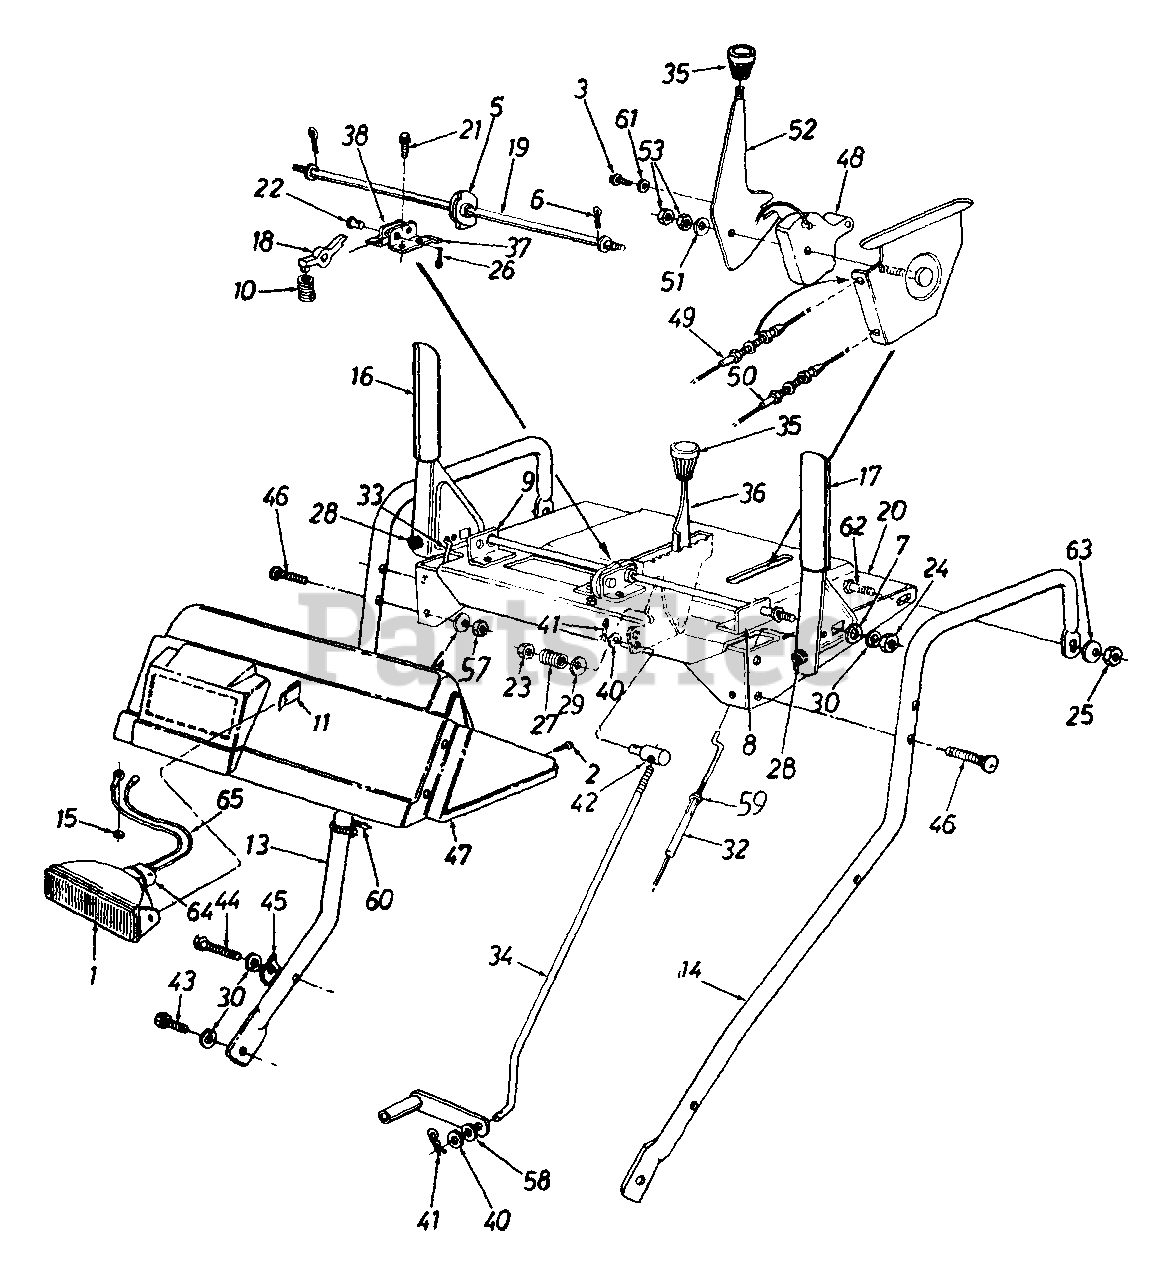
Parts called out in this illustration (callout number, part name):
1	Lamp Housing w/Lens
2	Truss Mach. B-Tap Scr. #10 x .5
3	Hex AB-Tap Scr. 1/4 x .62" Lg.
4	Bell - Wash. .325" I.D. x .88" O.D.
5	Cam Handle Lock
6	Cotter Pin 3/32" Dia. x .75" Lg.
7	Washer (Special) .72" O.D.
9	Handle Support Brkt. - R.H.
10	Compression Spring
11	Retaining Clip
13	Handle - R.H.
14	Handle - L.H.
15	Hex Sems Nut 1/4-20 Thd.t
16	Engagement Handle - R.H.
17	Engagement Handle - L.H.
18	Pawl Handle Lock
19	Rod Cam
22	Clevis Pin .437" Dia. x .65" Lg.
23	Hex Ins. L-Nut 3/8-24 Thd.
24	Hex Nut 5/16-18 Thd.
25	Hex Nut 1/4-20 Thd.
26	Cotter Pin 3/32" Dia. x 1" Lg.
27	Compression Spring
28	Rubber Bumper
29	Bell-Wash. .38" I.D. x .88" O.D.
30	L-Wash. 5/16" I.D.
31	Spring Wash. .265" I.D.
32	Auger Clutch Cable
33	Drive Clutch Cable
34	Shift Rod
35	Shift Knob
36	Shift Handle
37	Handle Brkt. - L.H.
38	Handle Brkt. - R.H.
40	Fl-Wash. .344" I.D. x .62" O.D.
41	Internal Cotter Pin 5/16" Dia
42	Ferrule
43	Hex Bolt 5/16-18 x .62" Lg. (Special)
44	Hex Bolt 5/16-18 x 1.75" Lg (Gr 5)
45	Handle Tab
46	Curved Carr. Bolt 5/16-18 x 1.5" Lg.
47	Handle Panel
48	Cable Guide
49	Chute Control Cable
50	Chute Control Cable w/Clip
51	Bell-Wash. .325" I.D. x .93" O.D.
52	Chute Tilt Handle
53	Hex Cent. L-Nut 5/16-18 Thd.
57	Hex Nut 5/16-18 Thd.
58	Spr. Wash. .32" I.D. x .62" O.D.
59	Hex Nut #10-24 Thd.
60	Cable Tie
61	Washer (Special) 1.25" O.D.
62	Hex Bolt 1/4-20 x .85" Lg.
63	Bell-Wash. .265" I.D. x .75" O.D.
65	Wire Harness
